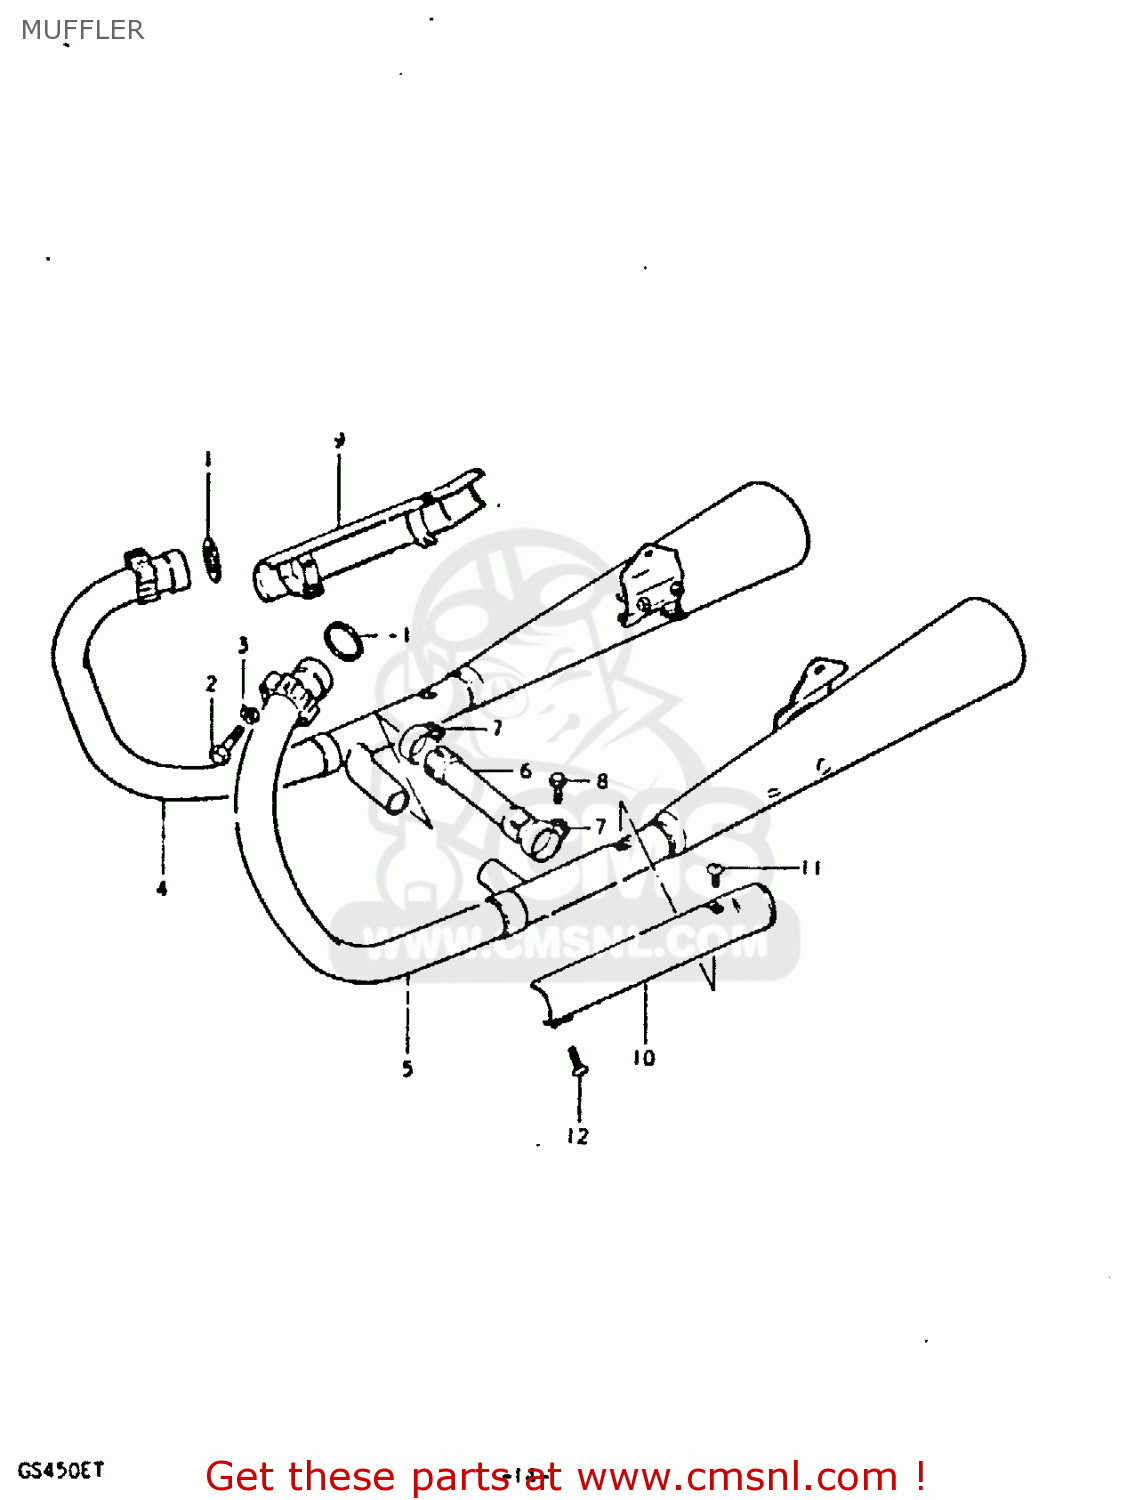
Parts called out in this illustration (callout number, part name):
1	GASKET,EXHAUST PIPE (NAS)
2	BOLT
3	LOCK WASHER
4	MUFFLER ASSEMBLY
5	MUFFLER ASSEMBLY
6	PIPE,EXHAUST COUPLER
7	CLAMP
8	BOLT
9	COVER,MUFFLER
10	COVER,MUFFLER
11	SCREW
12	SCREW
